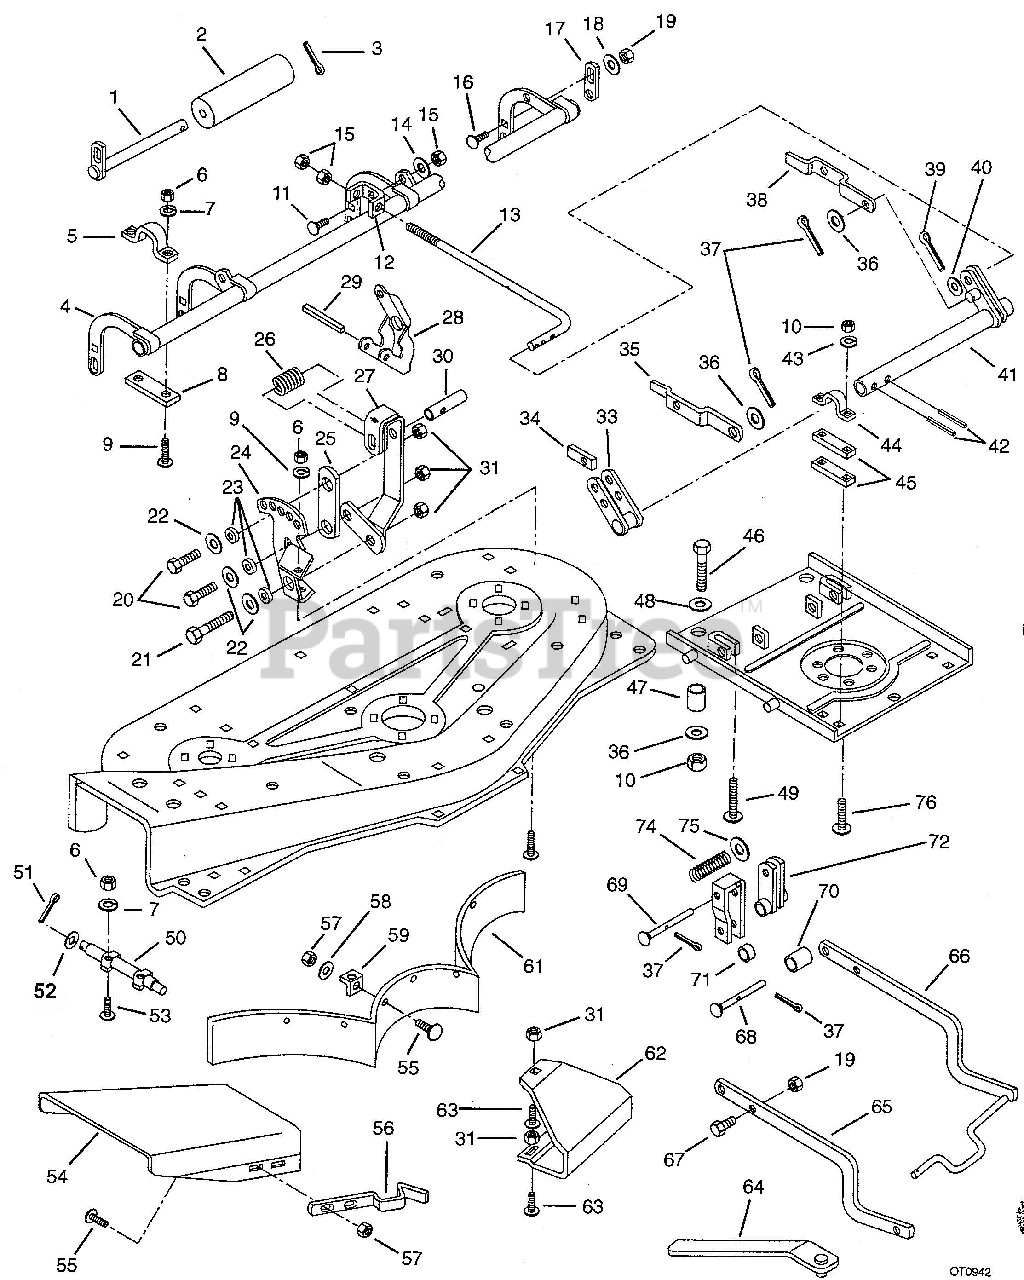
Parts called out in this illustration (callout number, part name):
1	ROLLER SHAFT
3	@PIN-CTR .18X1.00 EXTPRSQCT YZ
4	ROLLER FRAME 42 INCH
5	CLAMP
6	@NUT-HEX .31-18 YWZC
7	WSHR-LK .312X.097 HVY YWZC
8	ADJUSTMENT PLATE
9	BLT-RDHDSQNK .31-18X1.0 SHTYZ
10	@NUT-LK-CTR .50-13 YWZC
11	BLT-RDHDSQNK .50-13X1.25 G2YW
13	ADJUSTMENT ROD
14	WSHR-FL-STL .505X.880X.072 YWZ
15	@NUT-LK-CTR .50-13 YWZC
16	@BLT-RDHDSQNK .38-16X1.00 G2YZ
18	@WSHR-FL-STL.438X1.00X.083 YWZ
19	@NUT-LK-CTR .38-16 YWZC
20	@BLT-HEX .31-18X1.00 GR5 YWZC
21	@BLT-HEX .31-18X1.25 GR5 YWZC
22	WSHR-FL-STL .328X.875X.062YWZC
23	SPACER BUSHING .5 X .32 X .21
24	QUADRANT
26	SG-COMP .045X.50X1.187
27	HANDLE HEIGHT ADJ.
29	PIN-ROLL .188X1.75
31	@NUT-LK-CTR .31-18 YWZC
33	FRONT HANGER LINK
34	WEAR PLATE
35	LEVELING LEVER R.H.
36	WSHR-FL-STL .505X.880X.072 YWZ
37	@PIN-CTR .12X1.00 EXTPRSQCT YZ
38	LEVELING LEVER L.H.
39	@PIN-CTR .12X.75 EXTPRSQCT YWZ
40	@WSHR-FL-STL.50X1.25X.083 YWZC
41	FRONT HANGER
42	PIN-ROLL .250X1.25
43	WSHR-LK .500X.151 HVY YWZC
46	@BLT-HEX .50-13X2.50 GR5 YWZC
47	SPACER .512X.747X1.567
48	@WSHR-FL-STL.531X1.06X.095YWZC
49	@BLT-RDHDSQNK .50-13X1.75 G2YZ
50	HINGE PIN
51	@PIN-CTR .09X.75 EXTPRSQCT YWZ
52	@WSHR-FL-STL.406X.812X.065 YWZ
53	@BLT-HEX .31-18X.75 GR5 YWZC
54	CHUTE EXTENSION
55	BLT-RDHDSQSHNK.25-20X.50 YWZC
56	SPRING, FLAT
57	@NUT-LK-CTR .25-20 YWZC
58	@WSHR-FL-STL.281X.62X.065 YWZC
59	BAFFLE TAB
60	BLT-SERRDHD SL .31-18X.75 YZ
61	BAFFLE-42 IN PAN
62	SKID 42 INCH MOWER
63	@BLT-RDHDSQNK .31-18X.50 G5YZ
65	HANGER ARM
66	MOWER HANGER
67	@BLT-HEX .38-16X1.00 GR5 YWZC
68	PIN-CLEV .498X4.50 YWZC
69	PIN-CLEV .498X4.31 YWZC
70	SPACER .516X.749X.938
71	SPACER .390X1.000X.562
72	ARM
73	SUPPORT CHANNEL
74	SG-COMP .62X.68X1.75
75	@WSHR-FL-STL.531X1.06X.095YWZC
76	@BLT-RDHDSQNK .50-13X1.50 G5YZ
